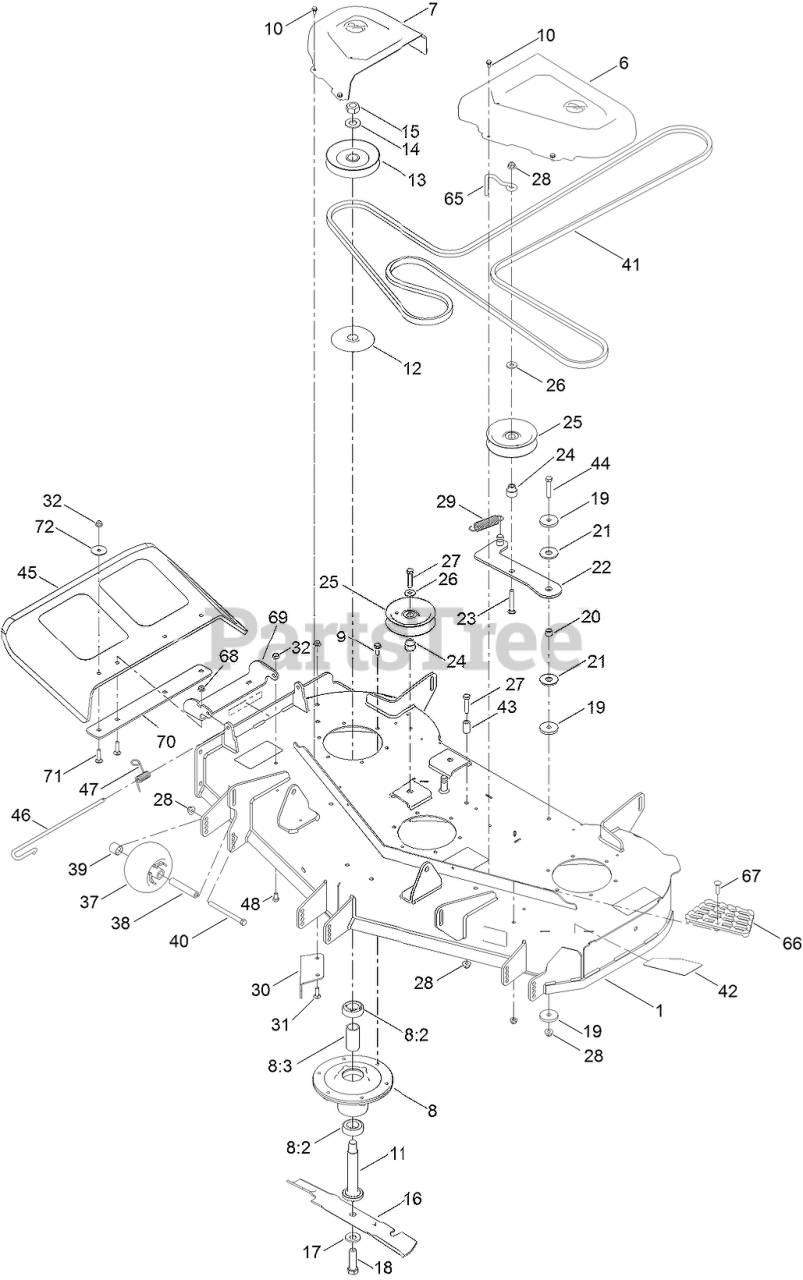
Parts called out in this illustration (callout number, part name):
1	48in DECK ASM
6	COVER-BELT, RH
7	COVER-BELT, LH
8	SPINDLE ASM
8:2	BEARING-BALL
8:3	SPACER-BEARING
9	SCREW-TAPTITE
10	SCREW-HWH
11	SHAFT-SPINDLE
12	SHIELD-BEARING
13	PULLEY
14	WASHER
15	NUT-HEX
16	BLADE-HI FLO, 16.50 INCH
17	WASHER-BELLEVILLE
18	SCREW-BLADE
19	WASHER-PLAIN
20	SPACER
21	WASHER-FRICTION, COMPOSITE
22	IDLER ARM ASM
23	SCREW-CARR
24	BUSHING-IDLER
25	PULLEY-IDLER, FLAT
26	WASHER-HARDENED
27	SCREW-HH
28	NUT-HF, NI
29	SPRING-EXTENSION
30	BAFFLE-CUTOFF
31	SCREW-CARR
32	NUT-HF, NI
37	ROLLER-SCALP, ANTI
38	TUBE-SPANNER
39	SPACER-AXLE, REAR
40	SCREW-HH
41	V-BELT
42	DECAL-DECK
43	SPACER-FENDER
44	SCREW-HH
45	DEFLECTOR
46	PIN-CHUTE
47	SPRING-TORSION
48	SCREW-HH
65	GUIDE-BELT, IDLER
66	STEP-DECK
67	BOLT-CARRIAGE
68	NUT-HF, NI
69	BRACKET-DEFLECTOR, UPPER
70	PLATE-DEFLECTOR
71	SCREW-CARR
72	WASHER-FLAT
